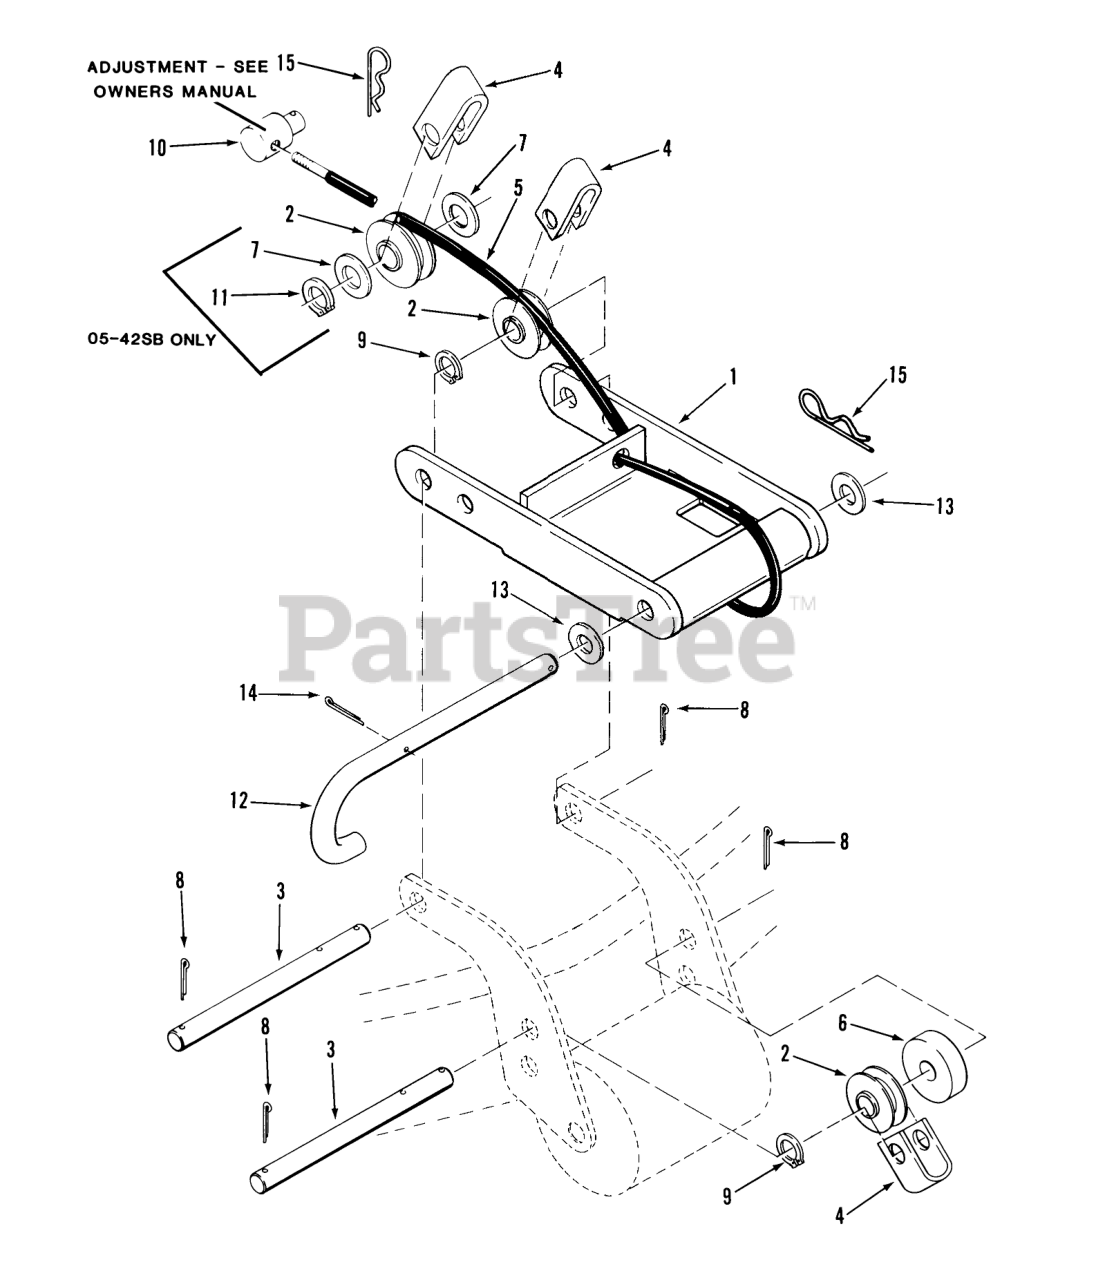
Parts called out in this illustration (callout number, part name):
1	Front Mount
2	ROLLER-CABLE
3	SPACER SEAT B
3	ROD CABLE ROLLER
4	STRAP-CABLE
5	ASSY-CABLE 36IN&42IN
6	SPACER
7	Washer
8	Pop Rivet
9	GRIP RING
10	TRUNNION
11	GRIP RING
13	Washer
15	Hairpin Cotter
